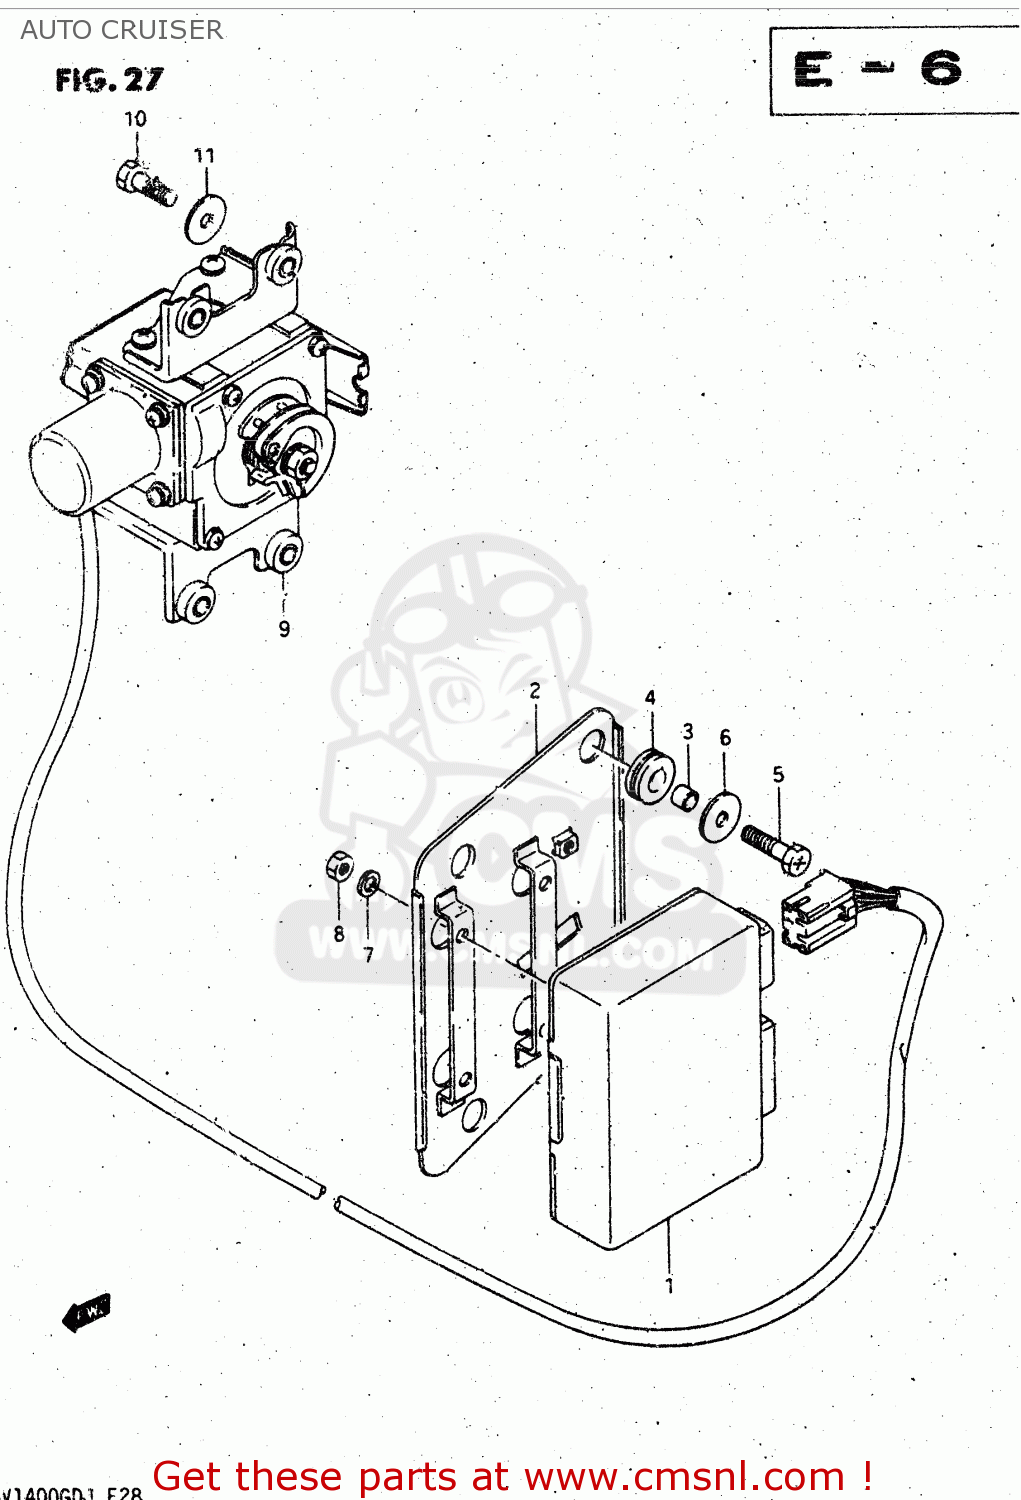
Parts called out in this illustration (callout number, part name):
1	CONTROLLER ASSEMBLY,AUTO CRUISE
2	BRACKET
3	SPACER (7X9X7)
4	CUSHION
5	SCREW
6	WASHER
7	LOCK WASHER
8	NUT
9	ACTUATOR ASSEMBLY,AUTO CRUISE
10	SCREW
11	WASHER (6.5X18X1.6)
